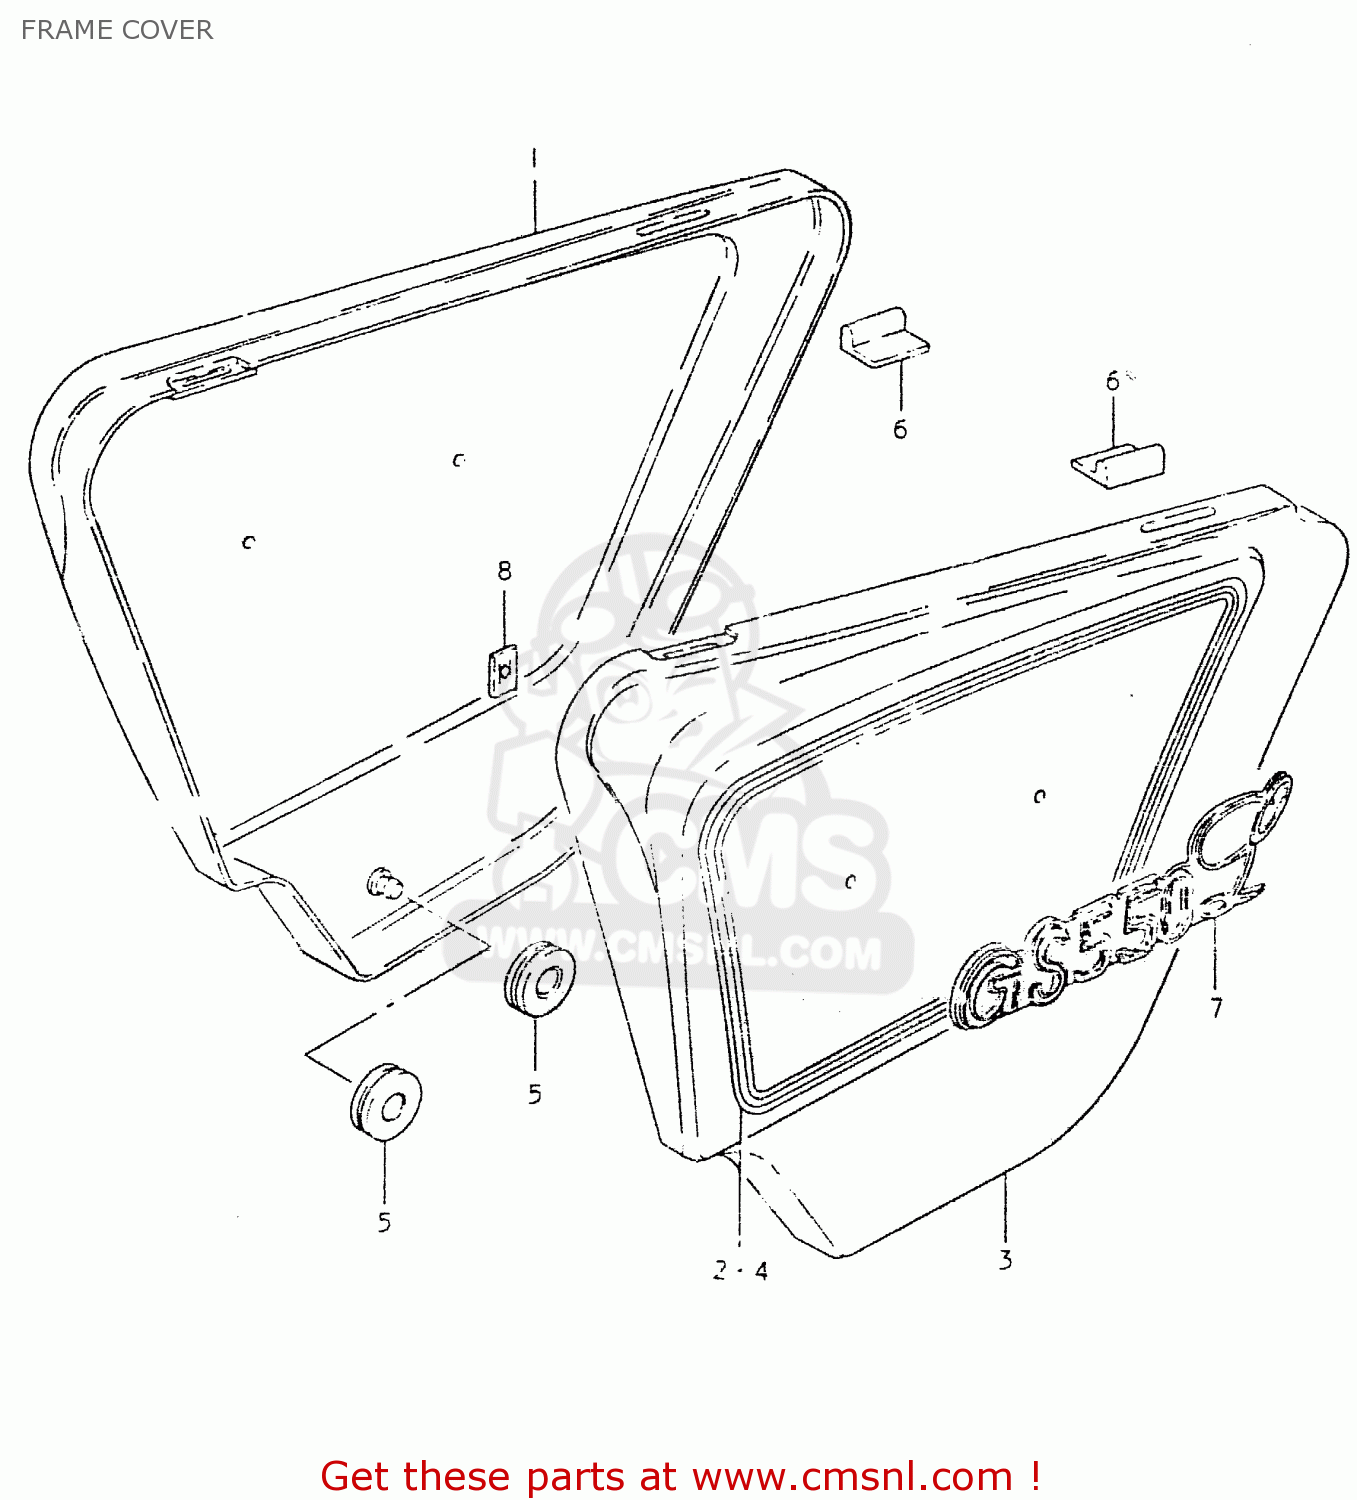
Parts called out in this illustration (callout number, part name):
1	COVER,FRAME,RIGHT
2	TAPE SET,FRAME COVER
3	COVER,FRAME,LEFT
4	TAPE SET,FRAME COVER
5	CUSHION
6	CUSHION,FRAME COVER
7	EMBLEM
8	NUT
